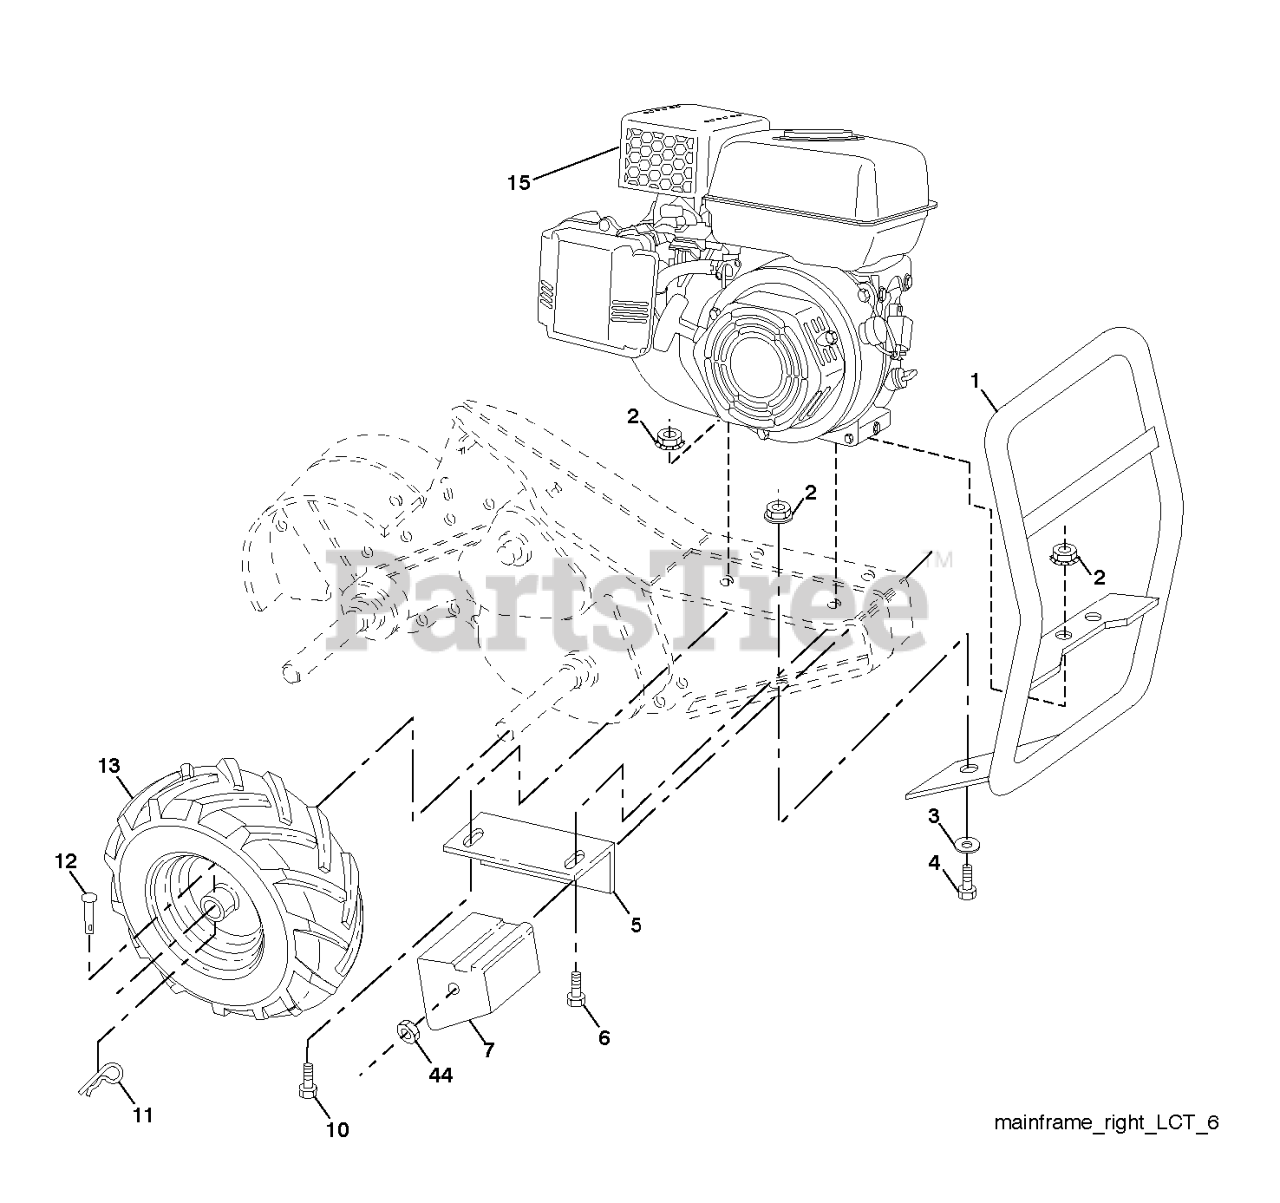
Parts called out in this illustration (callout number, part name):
1	BUMPER.ASM.TILLER.BLACK
2	LOCKNUT-FLANGE 5/16-18
3	WASHER
4	BOLT
5	BRACKET.REINFORCEMENT.RH.BLACK
6	BOLT, HEX 5/16-18X1-3/4
7	COUNTERWEIGHT.RH
10	BOLT
11	RETAINER M
12	RIVET
13	WHEEL.ASM.DRT.13X5-6.RT.SILVER
15	ENGINE LCT, 208CC, TILLER
